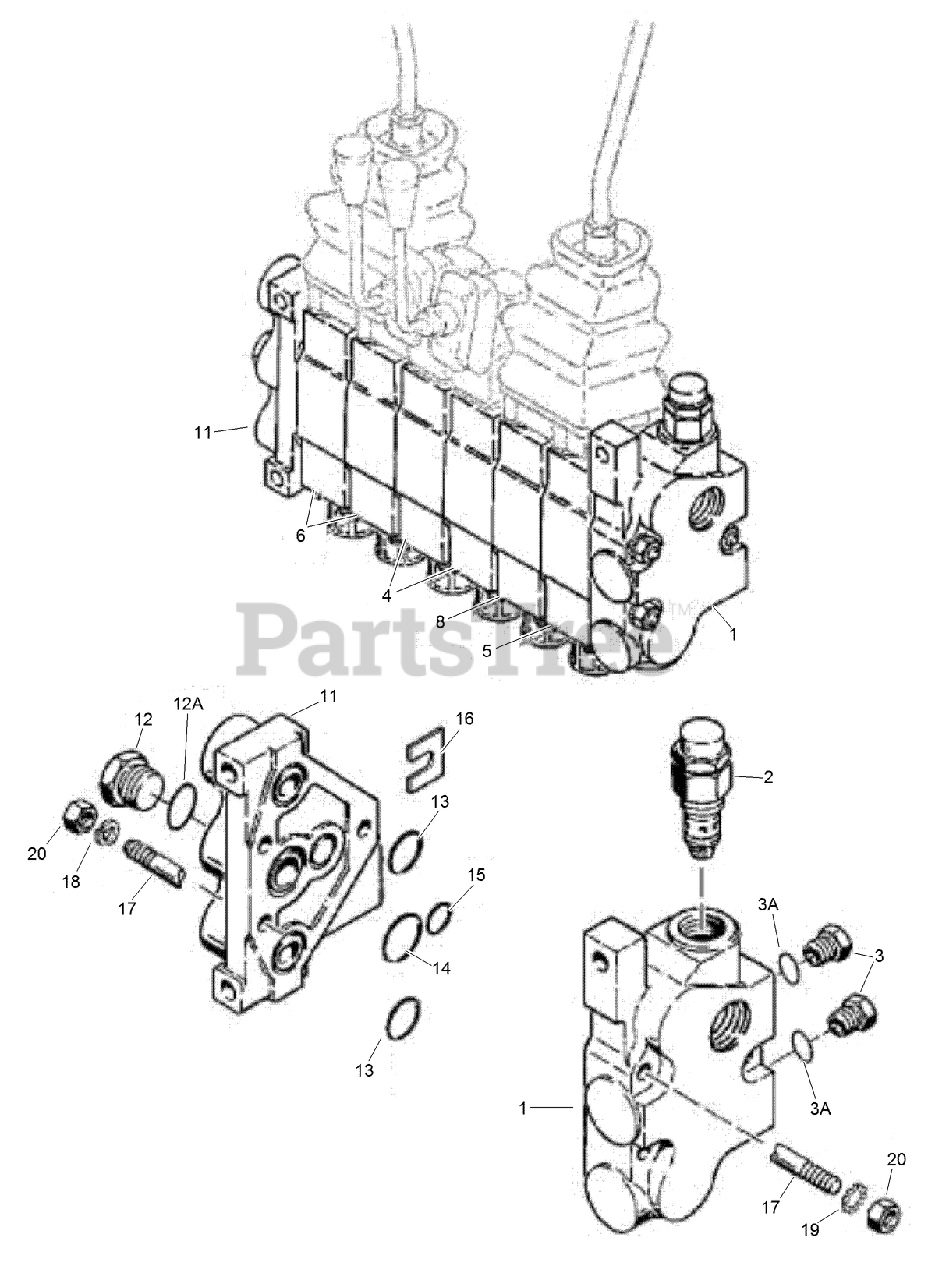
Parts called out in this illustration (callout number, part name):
1	ASSEMBLY - Inlet (Includes items 2, 3, & 3A)
2	VALVE - Relief
3	PLUG-Hex Hd, ORB 3/8
4	ASSEMBLY - Stabilizer
5	ASSEMBLY - Bucket
6	ASSEMBLY - Dipper, Swing
8	ASSEMBLY - Boom
11	ASSEMBLY - Outlet
12	PLUG-SOCKET HEAD
12A	O-RING
13	O-RING, Medium
14	O-RING, Large
15	O-RING, Small
16	SHIM - Adjusting
17	ROD - Tie
18	WASHER-Spring Lock, Reg 3/8 ZND
19	WASHER - Lock - 3/8
20	NUT - 3/8 NF
